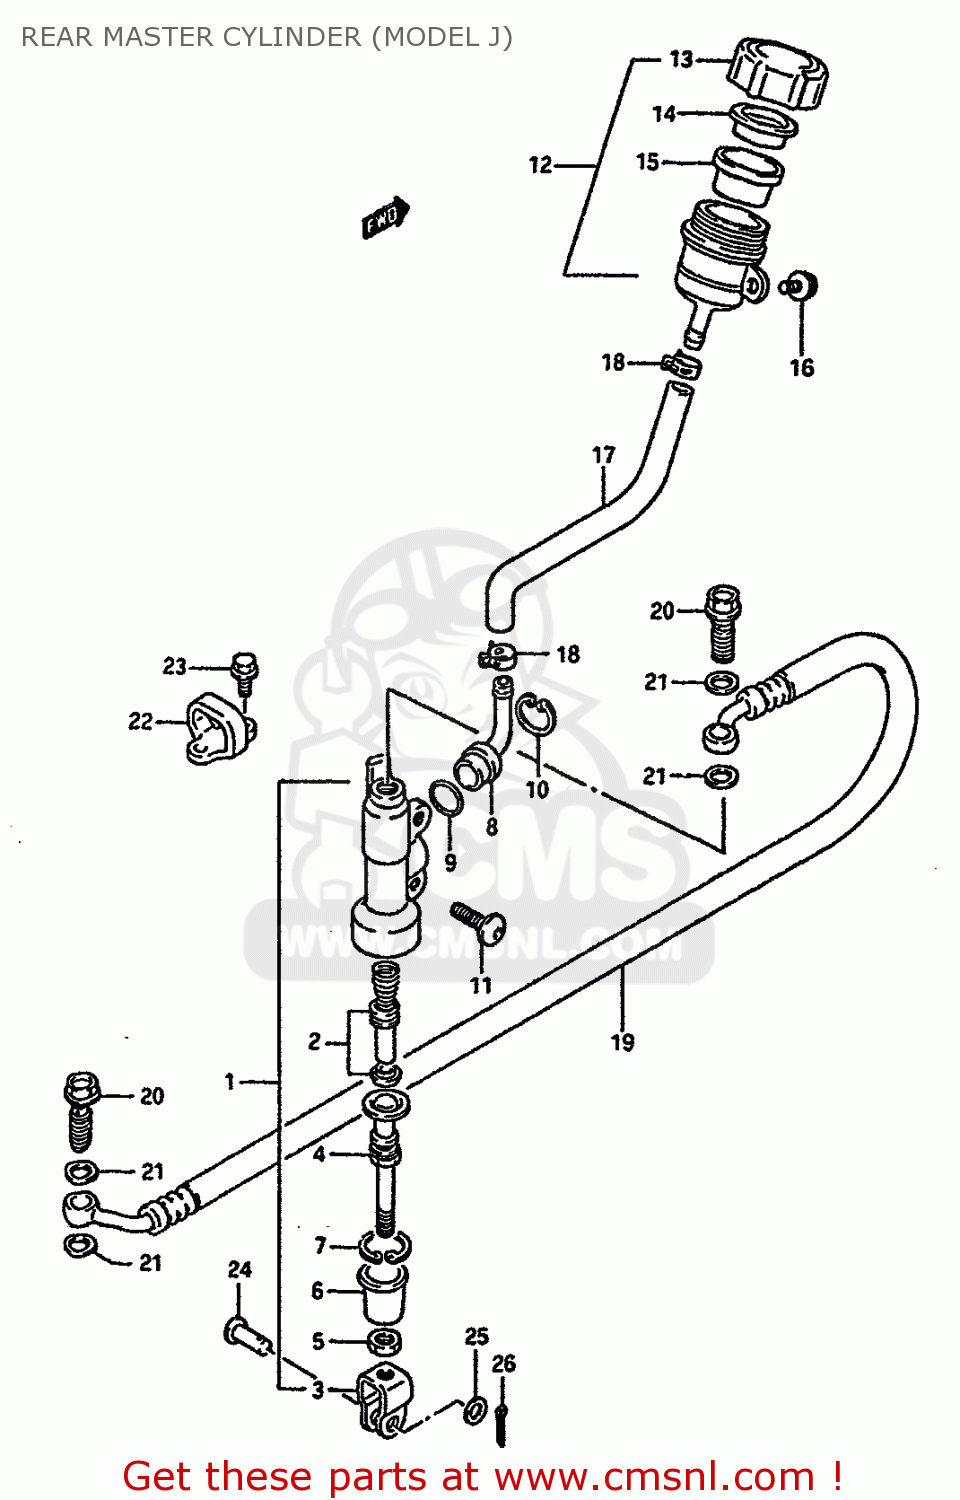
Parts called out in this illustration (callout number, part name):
1	CYLINDER ASSEMBLY,REAR MASTER
2	PISTON/CUP SET
3	YOKE
4	ROD,PUSH
5	NUT
6	BOOT
7	CIRCLIP
8	CONNECTOR
9	O RING
10	CIRCLIP
11	BOLT(6X18)
12	TANK ASSEMBLY,RESERVOIR
13	CAP
14	PLATE
15	DIAPHRAGM
16	BOLT
17	HOSE,RESERVOIR TANK
18	CLAMP,RESERVOIR HOSE
19	HOSE,REAR BRAKE
20	BOLT UNION
21	WASHER(10X15X1.5)
22	GUIDE,RR BRAKE HOSE
23	SCREW(5X10)
24	PIN(8X20)
25	WASHER(8.5X13X1.6)
26	PIN
